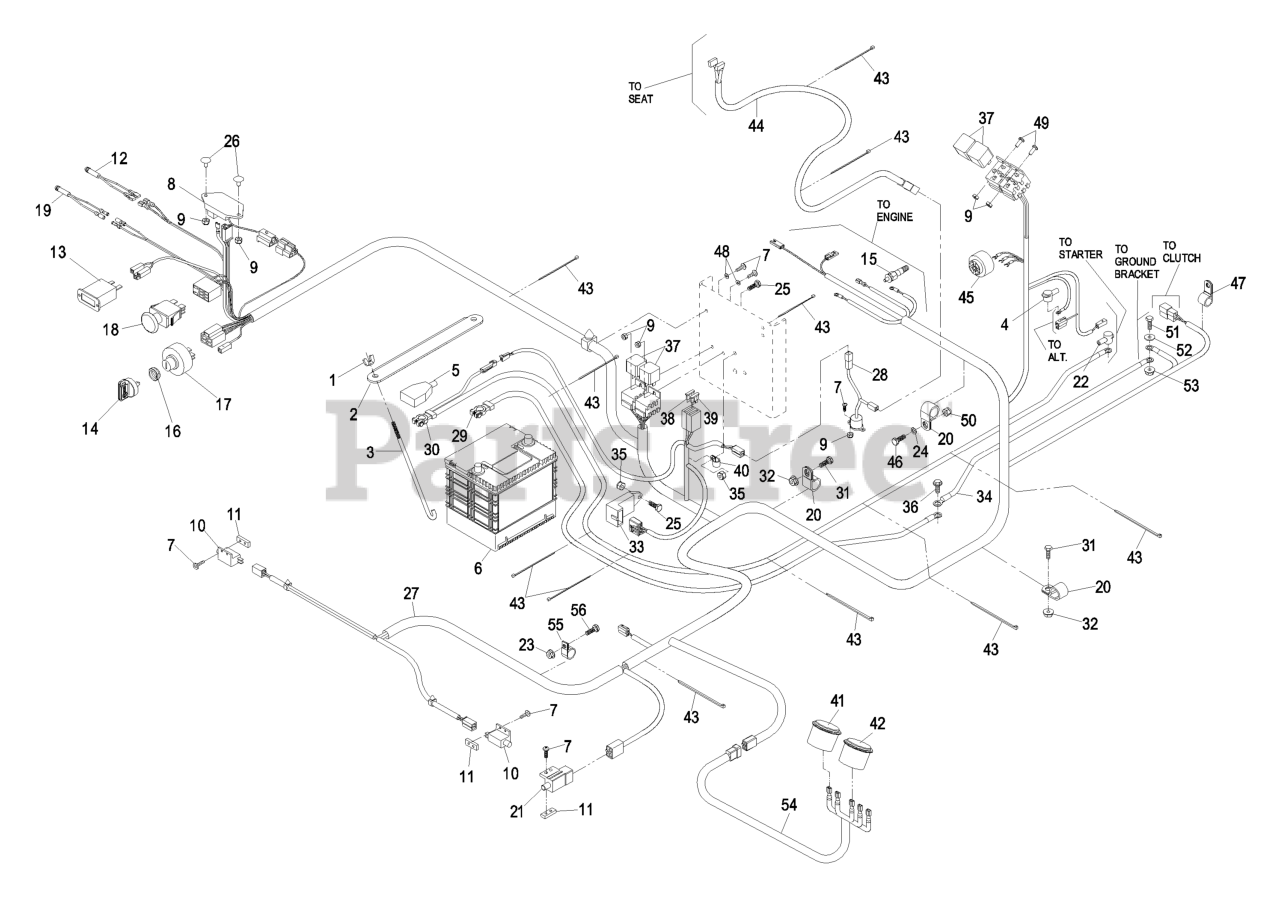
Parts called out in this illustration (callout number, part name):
1	WINGNUT
2	HOLDDOWN-BATTERY
3	BOLT-HOLDDOWN
4	CAP-INSULATOR, RED
5	INSULATOR-TERMINAL, BATTE
6	Battery, 12v SAE Post
7	SCREW-PPH
8	MODULE-DELAY, SEAT
9	NUT-LOCK, NI
10	SWITCH-OPEN, NORMALLY
11	PLATE-TAPPED
12	INDICATOR-LED, RED
13	METER-HOUR
14	KEY-IGNITION
15	SENDER-TEMPERATURE
16	NUT-SWITCH, IGNITION
18	SWITCH-PTO
19	INDICATOR-LED, AMBER
20	CLIP-LOOM
22	INSULATOR-STARTER
24	WASHER-FLAT
25	SCREW-HH
26	BOLT-CARR
27	HARNESS-WIRE
29	CABLE-BATTERY NEGATIVE
30	CABLE-STARTER
31	SCREW-HH
33	Briggs & Stratton P/N 820373 Module, Pre-Heat Timer
34	CABLE-ENGINE NEGATIVE
35	NUT-LOCK, NI
36	Screw-HWH 5/16-18 X 3/4 Tf
38	FUSE-BLADE TYPE, 20 AMP
39	FUSE-40 AMP
40	CLIP-LOOM
41	GAUGE-VOLTMETER
42	GAUGE-TEMPERATURE
43	TIE-PLASTIC
44	HARNESS-WIRING, SEAT
45	ALARM-TONE, DUAL
46	SCREW-HH
47	CLIP-LOOM
48	WASHER-FLAT
50	NUT-LOCK
51	SCREW-HH
52	WASHER-FLAT
53	NUT-HHF, WHIZ
54	HARNESS-GAUGE
55	CLIP-LOOM
56	SCREW-HH
